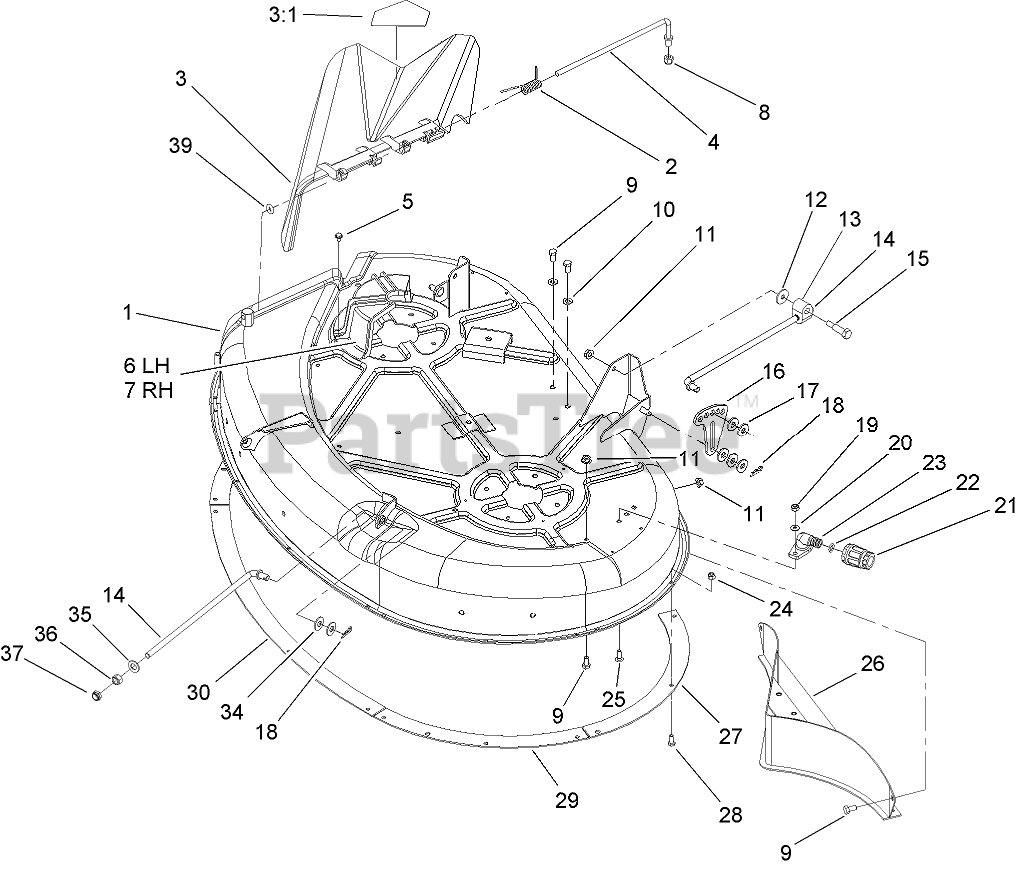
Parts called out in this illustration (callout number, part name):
1	42 Inch DECK ASM
2	SPRING
3	DEFLECTOR ASM
3:1	DECAL-DANGER
4	ROD-PIVOT
5	SCREW-HWHTF
6	GUIDE-BELT, LH
7	GUIDE-BELT, RH
8	NUT-LOCK, NI
9	SCREW-HH
10	WASHER-PLAIN
11	NUT-HF
12	WASHER-PIVOT
13	TRUNNION-HOC
14	ROD-HANGER
15	SCREW-SHOULDER, HH
16	LINK-ADJUSTING, HOC
17	WASHER-HARDENED
18	PIN-HAIR
19	NUT-LOCK, NI
20	WASHER-FLAT
21	CONNECTOR-HOSE
22	O-RING
23	FITTING-WASHOUT
24	NUT-LOCK, NI
25	BOLT-CARR
26	REAR BAFFLE ASM
27	RING-BLOW OUT, SIDE
28	SCREW-HH
29	RING-BLOW OUT, SIDE
30	RING-BLOW OUT
34	WASHER-FLAT
35	WASHER-FLAT
36	NUT-HEX
37	NUT-LOCK, NI
39	O-RING
